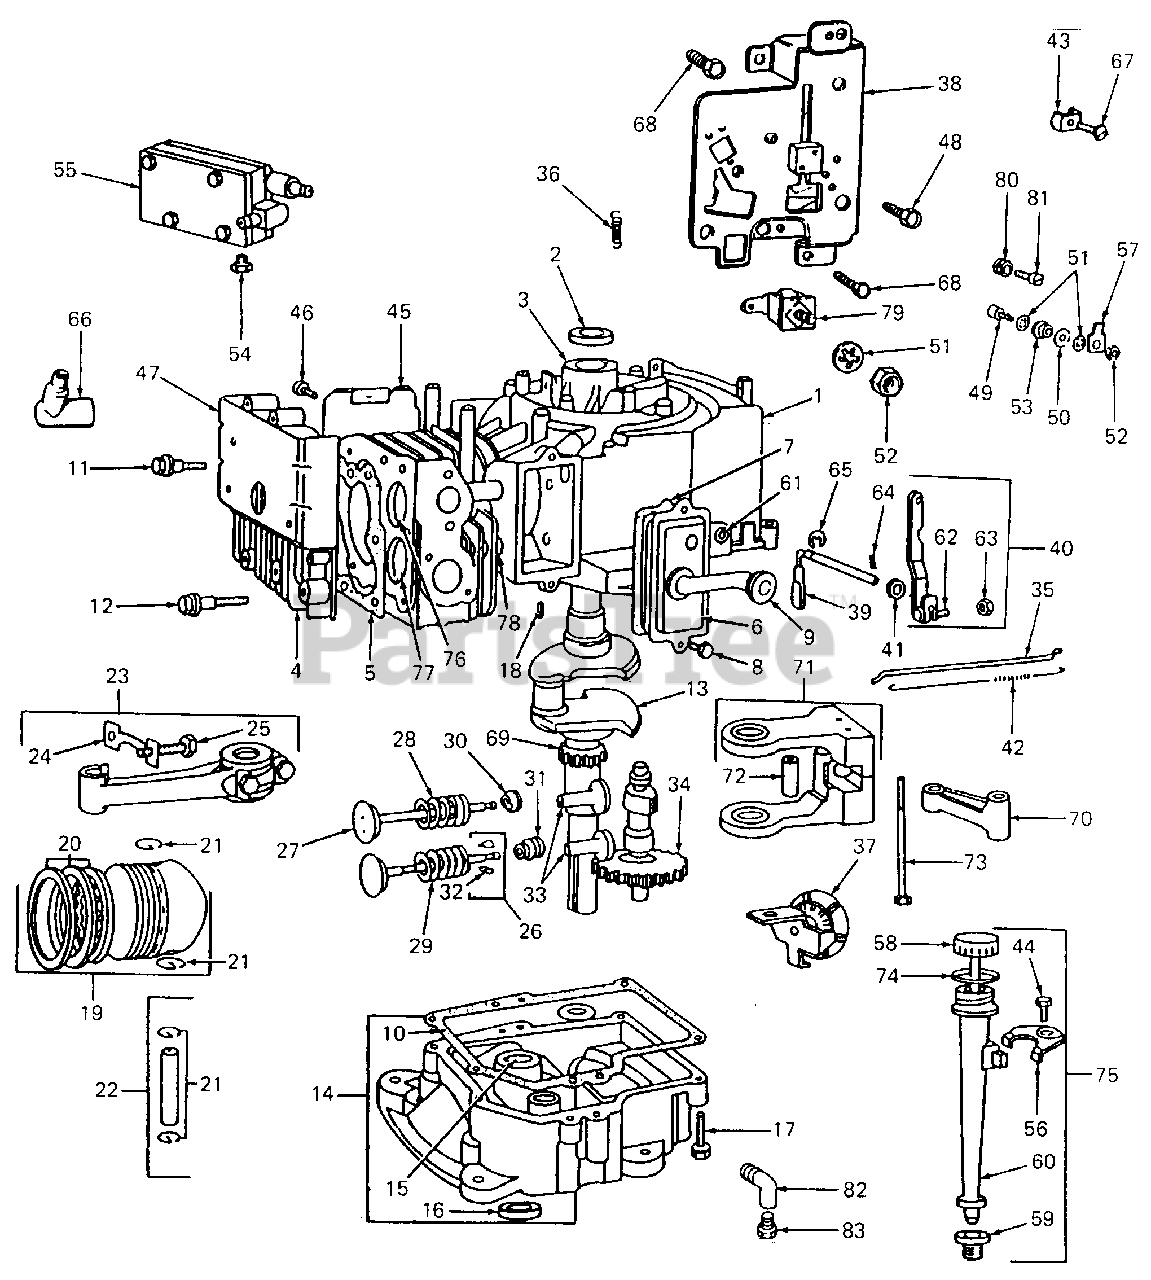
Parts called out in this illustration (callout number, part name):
1	Cylinder Assembly
2	Bearing Cylinder
4	Head, Cylinder
5	Gasket, Cylinder Head
6	Breather Assembly
7	Gasket, Valve Cover
8	Screw Sem
9	Tube, Breather
10	Gasket, Crankcase Cover 1/64 in. thick
11	Screw, Cylinder Head 2-21/32 in. Lg
12	Screw, Cylinder Head 3 in. Lg
13	Crankshaft
14	Base, Engine
15	Bushing, Engine Base
16	Seal, Oil
17	Screw, Base Mounting Sem
18	Key, Flywheel
19	Piston Assembly Std
20	Piston Ring Set Std
21	Lock, Piston Pin
22	Pin Assembly, Piston Std
23	Connecting Rod Assembly
24	Lock, Connecting Rod Screw
25	Screw, Connecting Rod
26	Valve, Exhaust
27	Valve, Intake
28	Spring, Intake Valve
29	Spring, Exhaust Valve
30	Retainer, Intake Valve
31	Rotocoil, Exhaust Valve
32	Retainer, Exhaust Valve Rotocoil
33	Tappet, Valve
35	Link, Governor
36	Spring, Governor
37	Oil Slinger, Governor Gear & Bracket Assy
38	Plate, Governor Control
39	Crank, Governor 1/4 in. dia.
40	Lever Assy, Governor for 1/4 in. dia. Crank
41	Washer, Governor Lever 1/4 in. dia.
42	Spring, Governor Link
43	Clamp, Casing
44	Screw, Clamp Mounting
45	Shield, Cylinder
46	Screw, Cylinder Shield Mounting Sem
47	Cover, Cylinder Head
48	Screw Sem
49	Screw, Terminal, Truss Hd
50	Washer, Insulating
51	Washer, Lock, Shakeproof
52	Nut, Hex 8-32
53	Collar, Insulating
54	Screw Sem
55	Pump, Fuel
56	Clamp, Oil Filler Tube
57	Terminal, Spade
58	Cap & Dipstick Oil Filler
59	Seal, Filler Tube
60	Tube, Oil Filler
61	Bushing, Governor Crank 1/4 in. I.D.
62	Bolt, Governor Lever
63	Nut, Hex 10-24
64	Cotter, Hair Pin
65	Retainer, E-Ring
66	Elbow, Spark Plug
67	Screw Sem
68	Screw
69	Gear, Timing
70	Link, Counterweight
71	Counterweight Assy
72	Pin, Counterweight
73	Screw, Counterweight
74	Seal, Filler Cap
75	Filler Group, Oil
76	Seat, Intake Valve Std
77	Seat, Exhaust Valve Std
78	Guide, Exhaust or Intake Valve
79	Insulator Assy
80	Spring, Throttle Adjustment
81	Screw, Machine Fill Hd. 8-3 X 1/2
82	Tube, Oil Drain
83	Plug, 3/8-18 Znp H/Hd Auto Pipe Oil Drain
